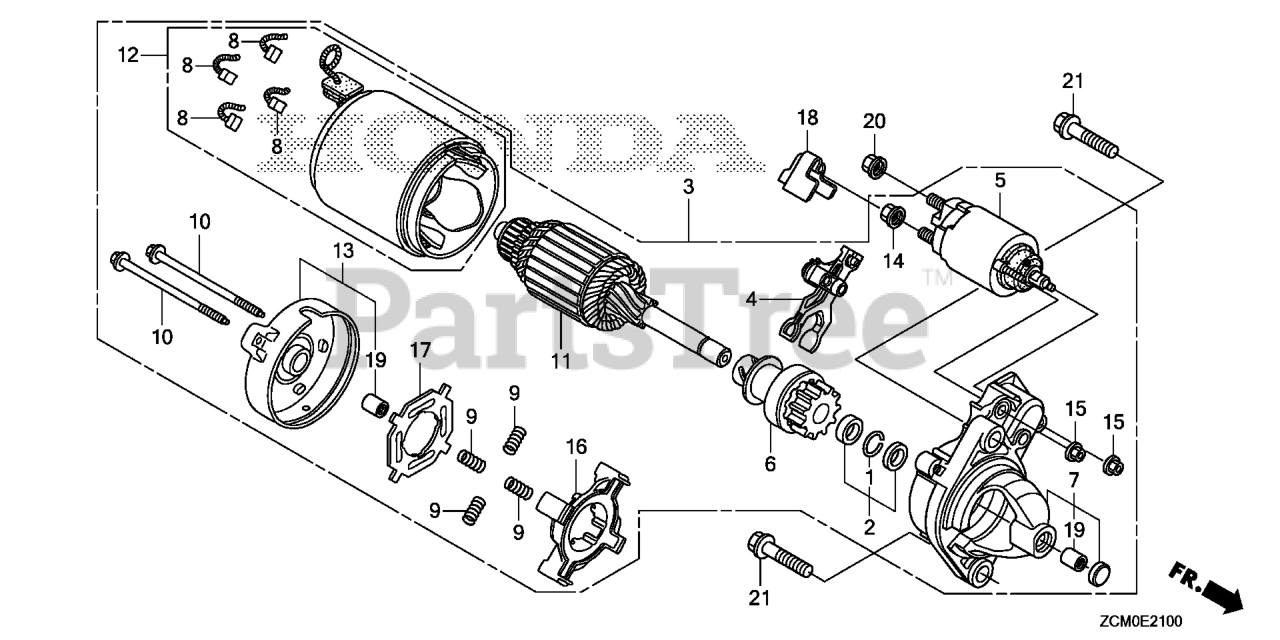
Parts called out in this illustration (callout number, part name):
1	RING, SNAP (DENSO)
2	COLLAR SET, CLUTCH STOP
3	STARTER MOTOR ASSY.
4	LEVER, PINION DRIVE
5	SWITCH ASSY., MAGNET
6	CLUTCH, OVERRUNNING
7	HOUSING, DRIVE SIDE
8	BRUSH
9	SPRING, BRUSH
10	BOLT, THROUGH
12	YOKE
13	FRAME, COMMUTATOR END
14	NUT, HEX. (8MM)
15	NUT, FLANGE (5MM)
16	HOLDER, BRUSH
17	INSULATOR, BRUSH HOLDER
18	COVER, TERMINAL
19	BEARING A
20	NUT-WASHER (8MM)
21	BOLT, FLANGE (10X40)
